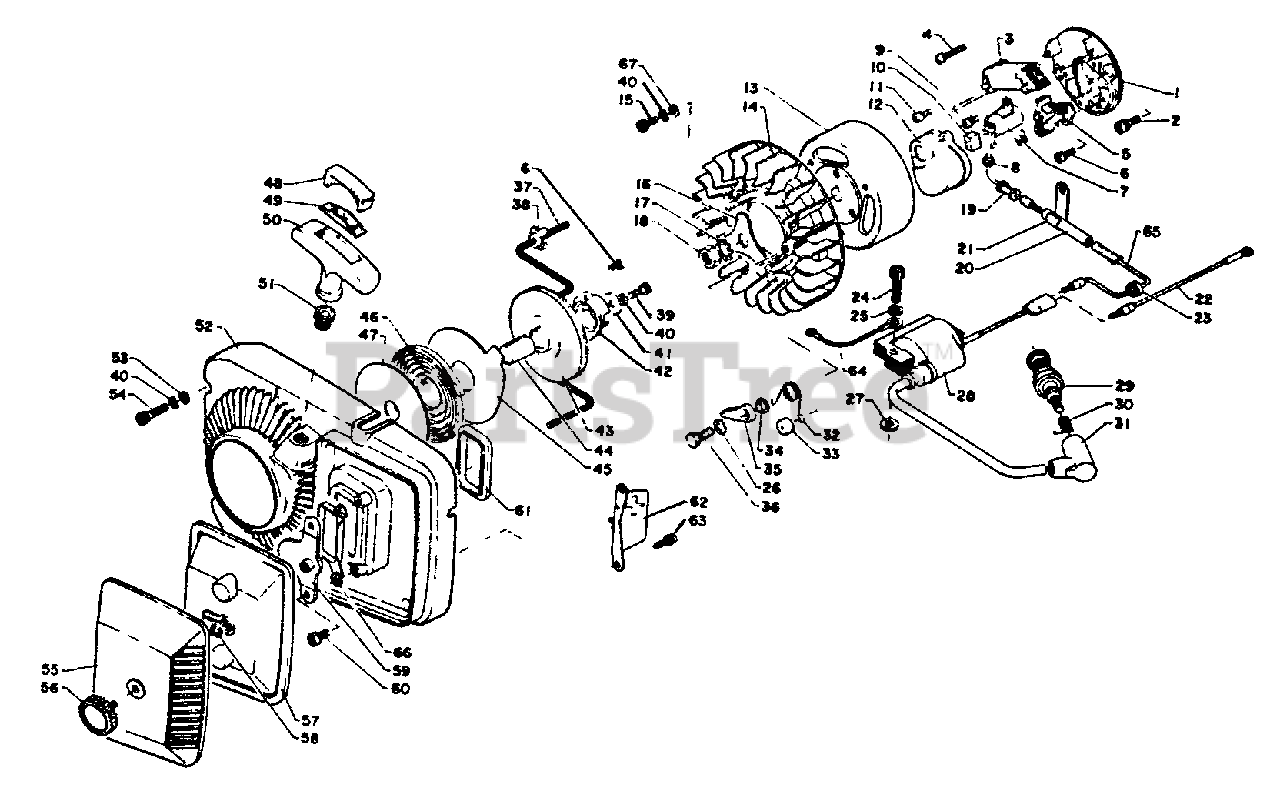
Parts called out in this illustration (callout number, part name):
1	PLATE, STATOR
2	SCREW 5×18
3	PRIMARY IGNITION COIL
4	SCREW 4×25
5	CONTACT POINT SET
6	SCREW - 4×10
7	CONDENSER 1
8	RUBBER BUSHING
9	SCREW - 4×10
10	OILER (0.1 FELT)
11	SCREW 4×12
12	COVER, BREAKER
13	FLYWHEEL
14	FAN
15	BOLT 5×12
16	WASHER
17	WASHER, LOCK
19	RUBBER BUSHING
20	COVER TUBE
21	CLIP
22	LEAD - GROUND
23	GROMMET
24	SCREW - 5×25
25	WASHER, SPRING 6
26	WASHER - 6
27	WASHER 6
28	COIL, IGNITION
29	SPARK PLUG - BPM7A
30	TERMINAL, SPARK PLUG CAP
31	CAP, SPARK PLUG
32	SPRING, RETURN
34	SPACER
35	PAWL, STARTER
36	BOLT - 6×14
37	ROPE, STARTER
38	RETAINER, ROPE
39	SCREW - 5×15
40	WASHER, SPRING 5
41	WASHER 5.5×18×1
42	CATCHER, PAWL
43	REEL, ROPE
45	PLATE, STARTER
46	SPRING, REWIND
47	PLATE, SIDE
48	CAP
49	RING, RETAINING
50	GRIP, STARTER
51	GUIDE, ROPE
52	CASE, STARTER
53	WASHER, FLAT 5.5×10×0.8
54	BOLT 5×20
55	COVER, AIR FILTER
56	THUMBSCREW
57	FILTER, AIR
58	E-RING 4
59	PLATE, PREVENT
60	SCREW 5×10
61	O-RING
62	GUIDE PLATE. COOLING AIR
63	SCREW 4×12
64	LEAD - GROUND
65	LEAD - GROUND
66	SEAL PACKING HOLDER
67	WASHER, FLAT 5.5×10×0.8
